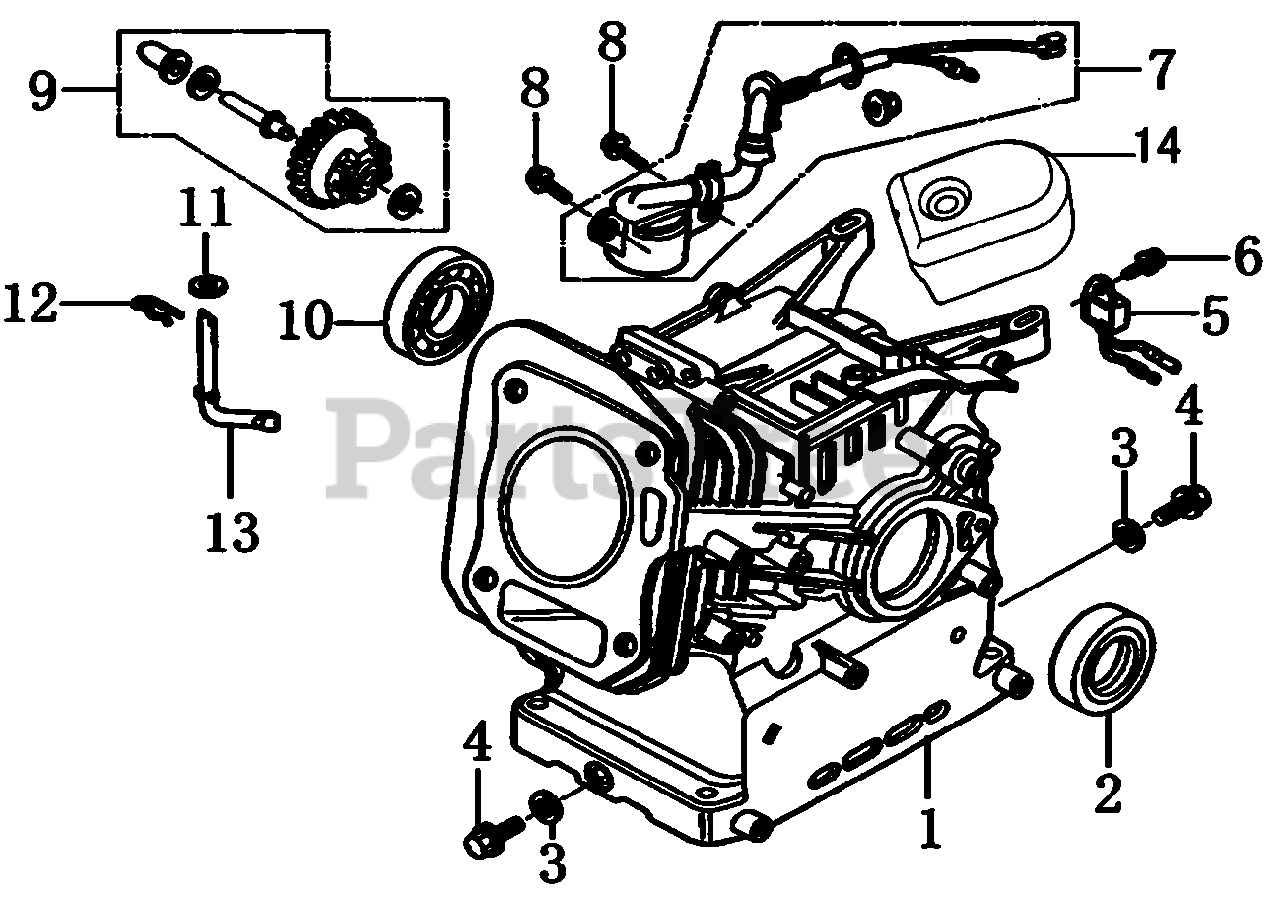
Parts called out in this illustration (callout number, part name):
1	CRANK CASE
2	OIL SEAL 25x41.25x6
3	WASHER, DRAIN PLUG
4	BOLT, DRAIN PLUG
5	ALERT UNIT, OIL
6	BOLT, FLANGE, 6x10
7	OIL LEVEL SWITCH
8	BOLT, FLANGE, 6x14
9	GOVERNOR GEAR ASSY.
10	BEARING, RADIAL BALL
11	WASHER, PLAIN
12	PIN, LOCK
13	SHAFT, GOVERNOR ARM
14	WIRE COVER, OIL LEVEL SWITCH WIRE CONNECTIONS
